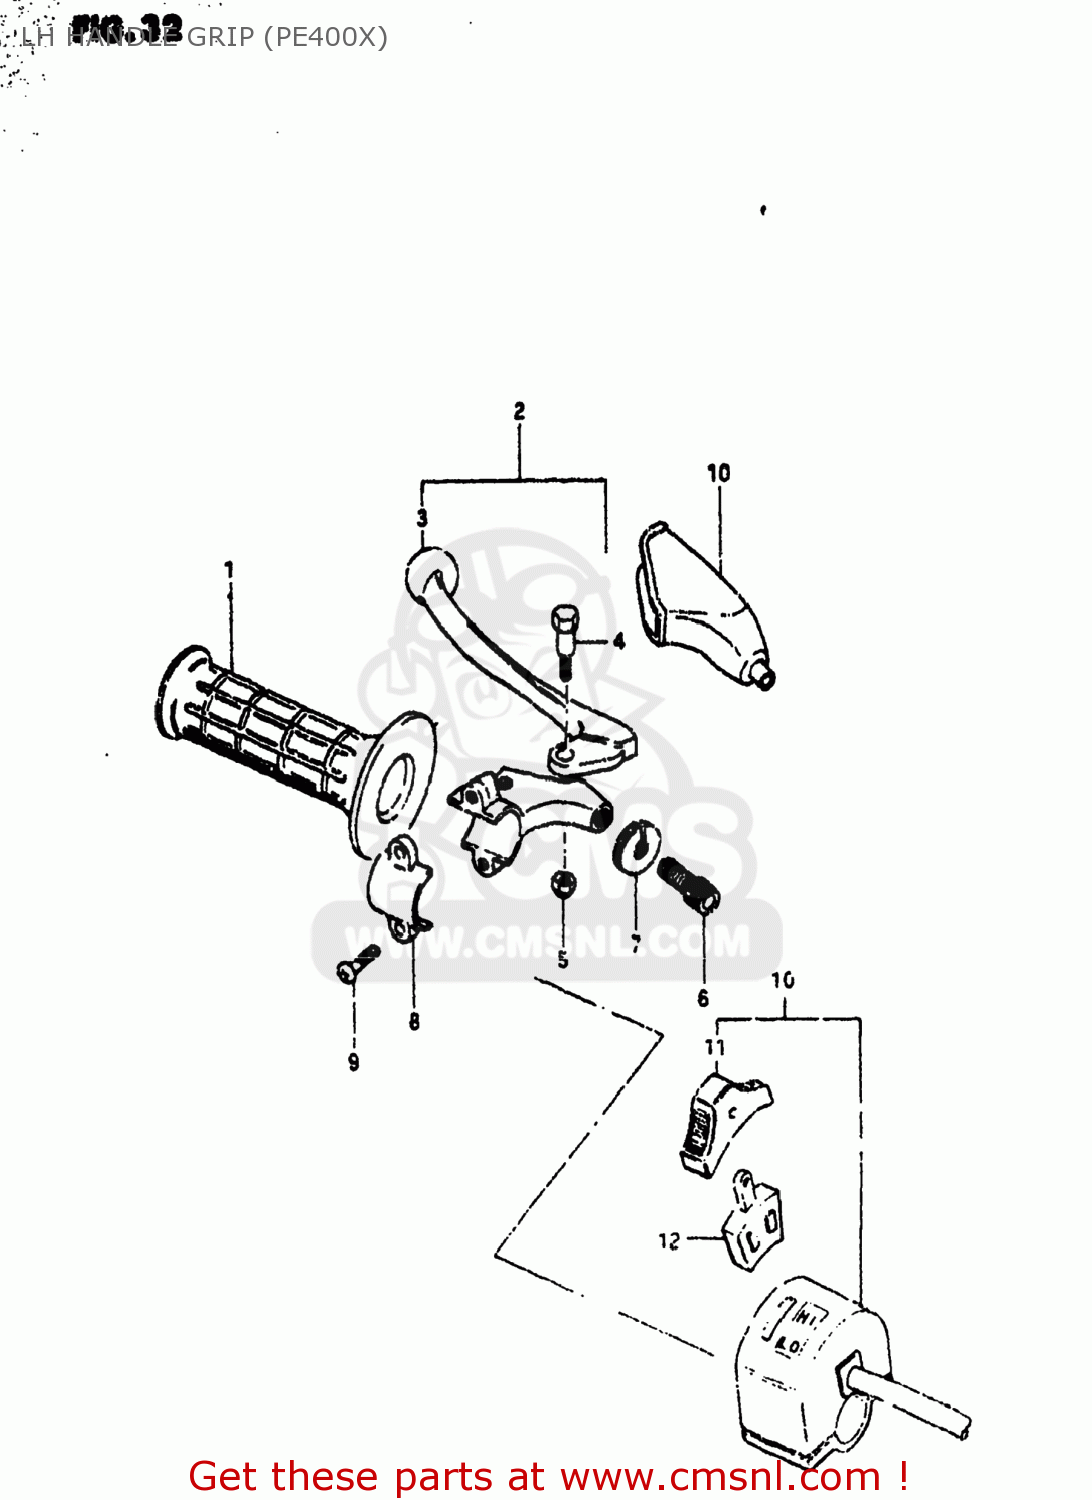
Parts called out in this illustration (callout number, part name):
1	GRIP,LEFT
2	LEVER ASSEMBLY
3	LEVER,CLUTCH
4	BOLT,LEVER
5	NUT 6MM
6	ADJUSTER,CABLE
7	NUT,CABLE ADJUSTER
8	BRACKET,LEVER
9	SCREW
10	SWITCH,DIMMER
11	KNOB,LIGHTING & DIMMER
12	BLOCK,LIGHTING/DIMMER
13	COVER,CLUTCH LEVER
